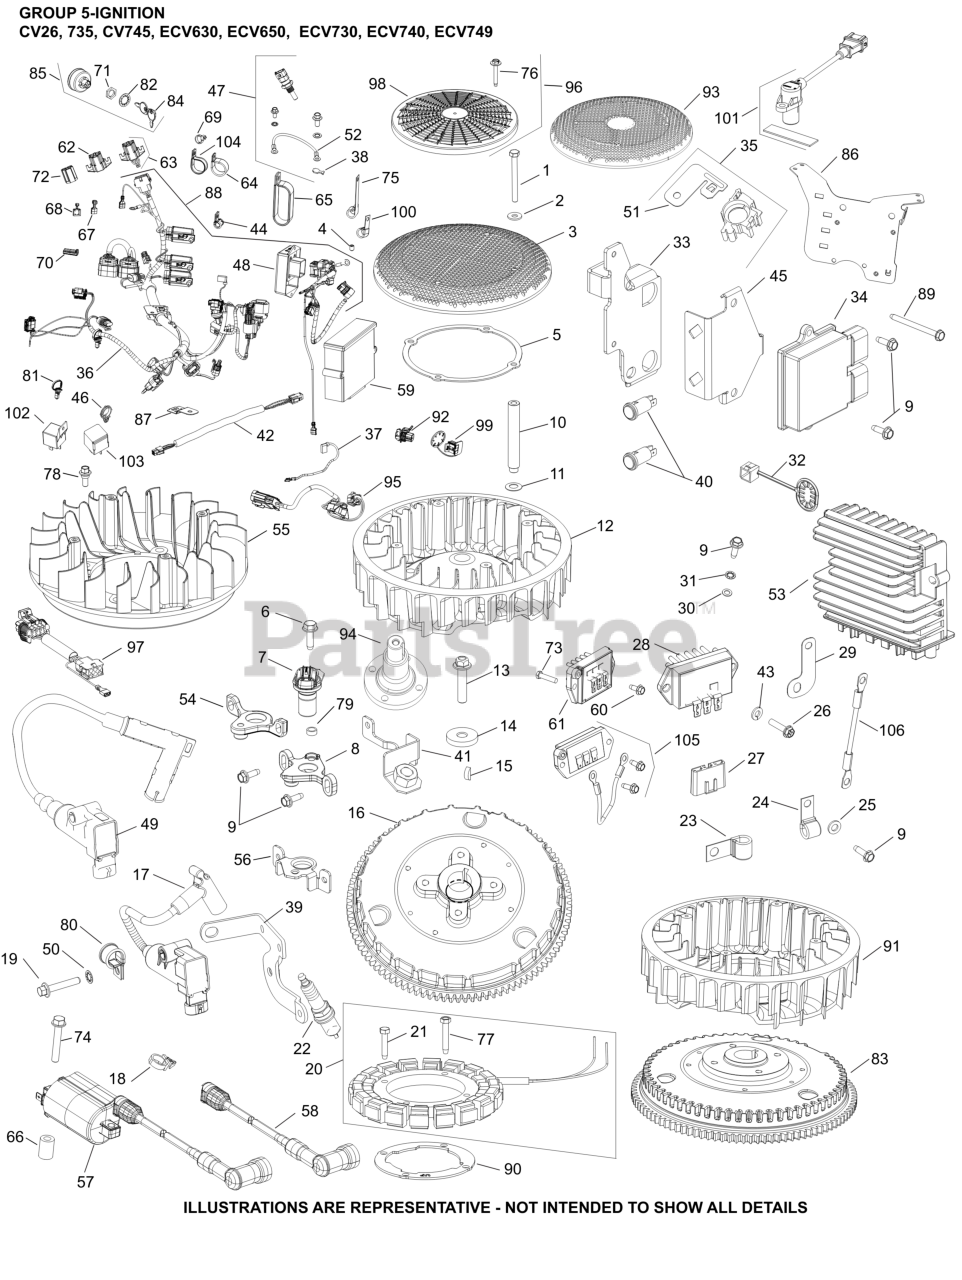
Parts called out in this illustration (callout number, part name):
1	SCREW, CAP M6X1.0X99.5
2	WASHER, FLAT 1/4" (O.D. 5/8")
3	SCREEN, GRASS
4	SCREW, SKT SET #10-24X1/4"
5	RING, SUPPORT
7	SENSOR, SPEED
9	SCREW, THREAD FORMING
11	WASHER, SPRING 10 MM
13	SCREW, HEX FLANGE
14	WASHER, FLAT
15	KEY, 3/16" X 5/8"
19	SCREW, THD FRM-USE 25 086 473-S
19	SCREW, HEX FLANGE
20	KIT, 15 / 20 AMP STATOR
21	SCREW, THREAD FORMING
22	SPARK PLUG, RFI
25	WASHER, FLAT 1/4" (O.D. 1/2")
26	SCREW, HEX FLANGE HI-LO
27	CONNECTOR
31	WASHER, INT TOOTH LOCK #10
32	CAP, CONNECTOR
33	BRACKET, ECU
34	MODULE, ECU ECV740
36	HARNESS, WIRING (EFI-MECH.GOV)
46	RETAINER, WIRE HARNESS
49	COIL, IGNITION - EFI (RFI/EMC)
50	WASHER, INT TOOTH LOCK 1/4"
56	BRACKET, SENSOR
60	SCREW, THREAD FORMING
61	REGULATOR, RECTIFIER (20-30AMP,FW W/OVP)
65	CLAMP, INSULATED DOUBLE
100	CLIP, CABLE (KM)
104	CLAMP, INSULATED
NI	FLYWHEEL, ASSEMBLY-USE 24 025 115-S
